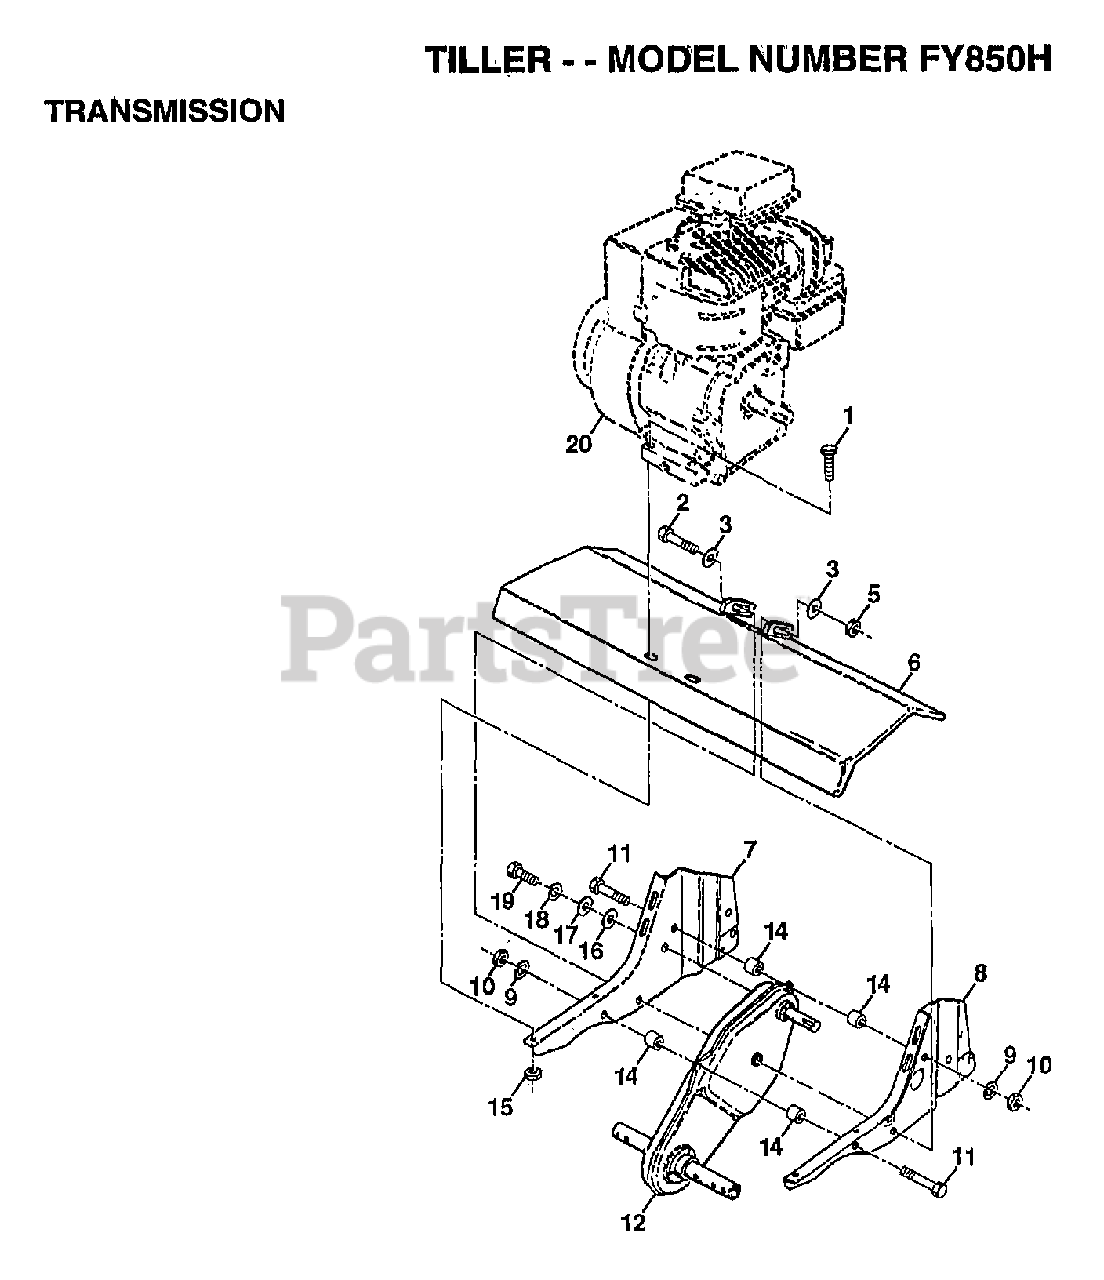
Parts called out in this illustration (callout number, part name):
1	BOLT.HEX.5/16-1.5
2	BOLT HEX 3/8-16
3	WASHER
5	NUT
6	"SHIELD, TINE"
7	BRACKET.ENGINE.RH
8	ENGINE BRKT LH TI
9	LOCKWASHER
10	NUT.HEX.5/16-18
14	SPLIT SPACER RT
16	WASHER
17	WASHER
18	LOCKWASHER
19	BOLT
